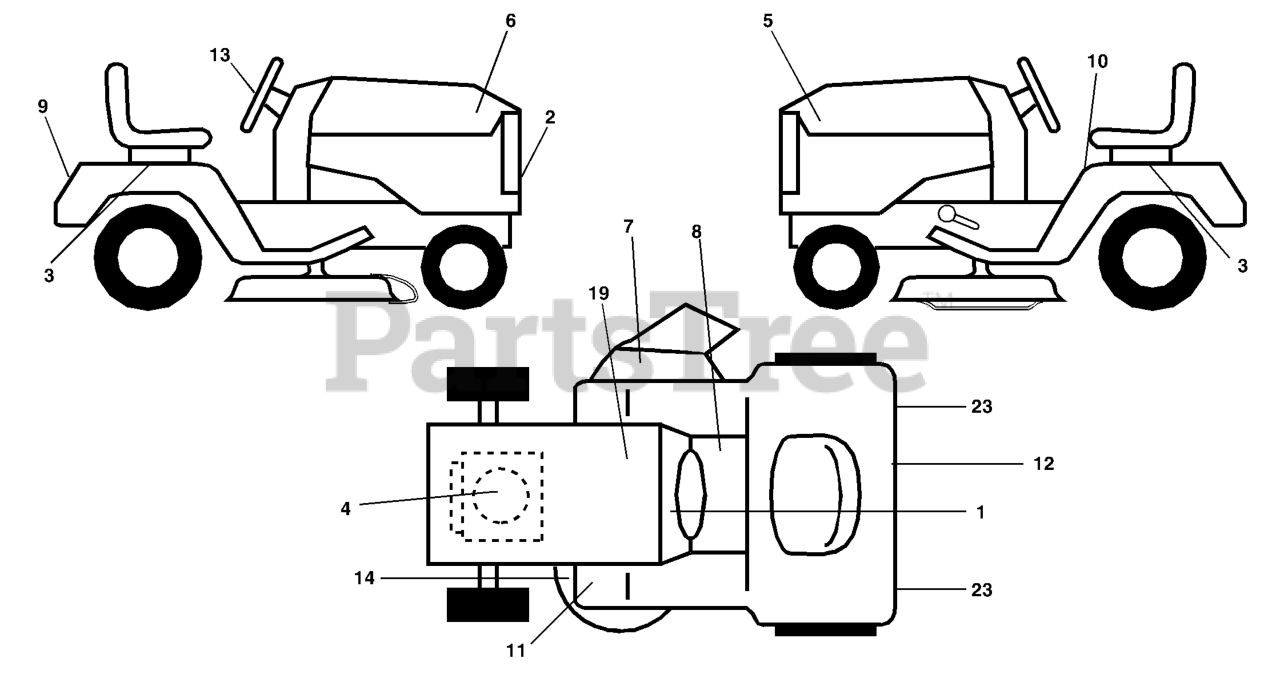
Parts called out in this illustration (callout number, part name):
1	DECAL, OPERATING INSTRUCTIONS
2	DECAL.GRILLE.HUSQ
3	DECAL, FENDER
4	Decal, HP Engine
5	DECAL, HOOD LH GTH220 HYDRO
6	DECAL HOOD RH GTH220 HYDRO
7	DECAL WARNING (ENGLISH/FRENCH)
8	DECAL PARK BRAKE
9	DECAL FENDER HUSQ
10	DECAL FENDER DANGER
12	DECAL D-BAR
13	Decal, SW Deluxe
14	DECAL V-BELT SCHEMATIC
19	DECAL BTRY SYMBOLS
23	REFLECTOR-TAIL YT
